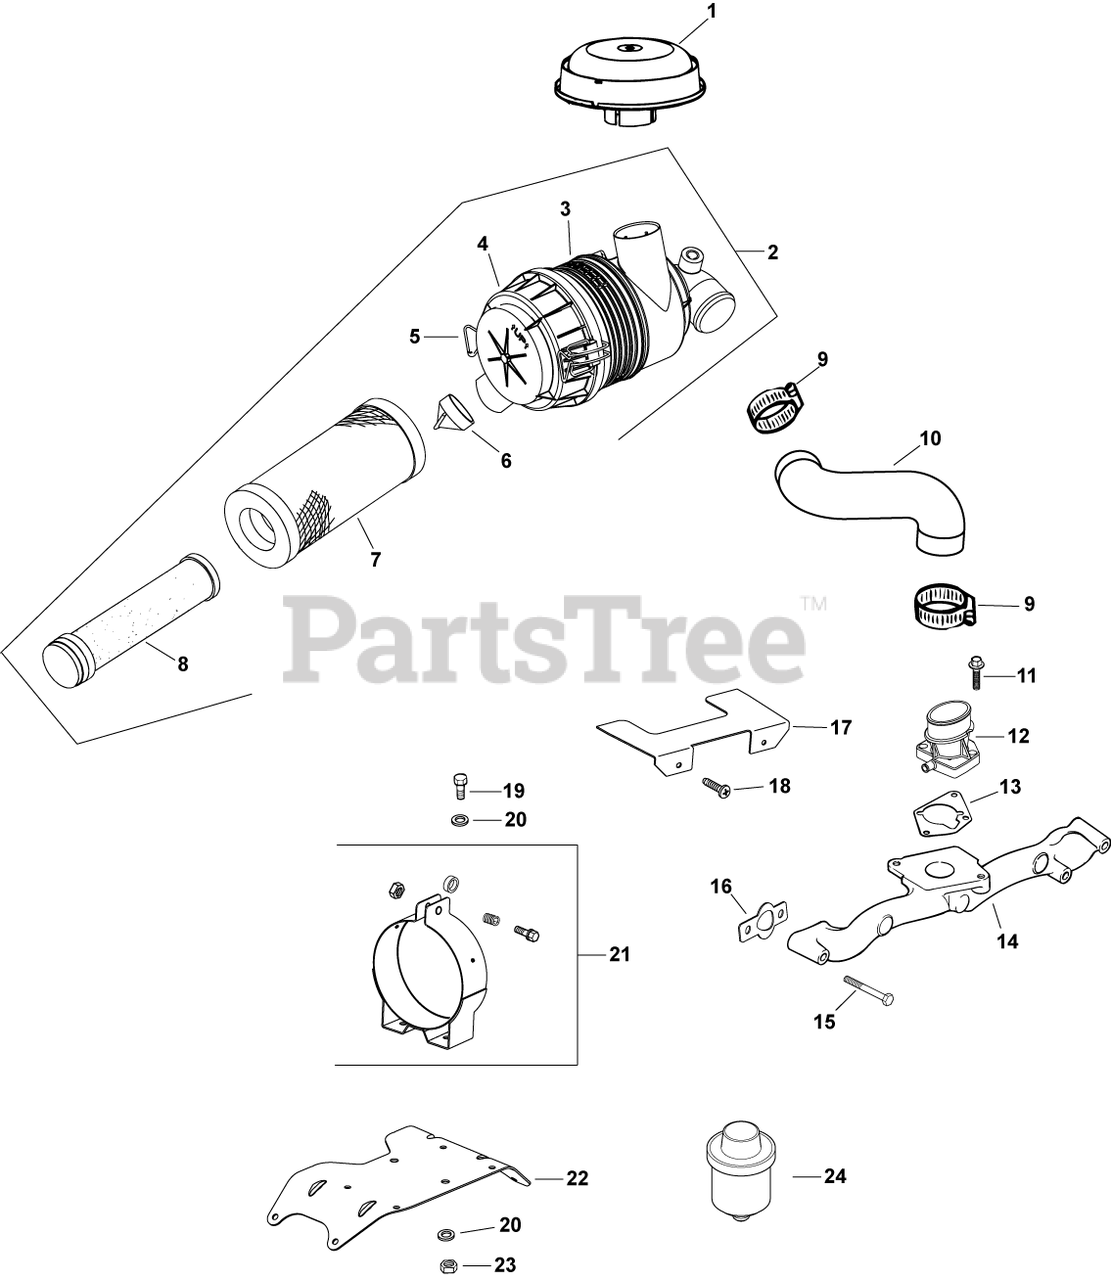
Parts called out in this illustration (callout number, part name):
1	HOOD, AIR CLEANER (5.25)-USE 25 324 04-S
2	CLEANER, AIR-USE 25 048 17-S
3	HOUSING, HD AIR CLEANER
4	COVER ASSEMBLY, AIR CLEANER
5	CLIP - USE 62 154 07-S
6	VALVE, DUST EJECTOR
7	ELEMENT, AIR FILTER - PRIMARY
8	ELEMENT, AIR FILTER - SAFETY
9	CLAMP, HOSE
10	HOSE, AIR CLEANER
11	SCREW, FLG M6X1.0X16
12	ADAPTER, AIR CLEANER -USE 24 029 82-S
13	GASKET, AIR CLEANER BASE
14	MANIFOLD, METAL INTAKE
15	SCREW, FLG M6X1.0X55
16	GASKET, INTAKE MANIFOLD USE 24 041 79-S
17	SHIELD, DEBRIS
18	SCREW, PHL HD 11-16X3/4"
19	SCREW - USE 25 086 124-S
20	WASHER, FLAT 1/4" (O.D. 1")
21	BRACKET, AIR CLEANER-USE 24 126 191-S
22	BRACKET, AIR CLEANER
23	NUT, LOCK M6X1.0
24	KIT, AIR FILTER SENSOR
24126146-S	BRACKET, AIR CLEANER
